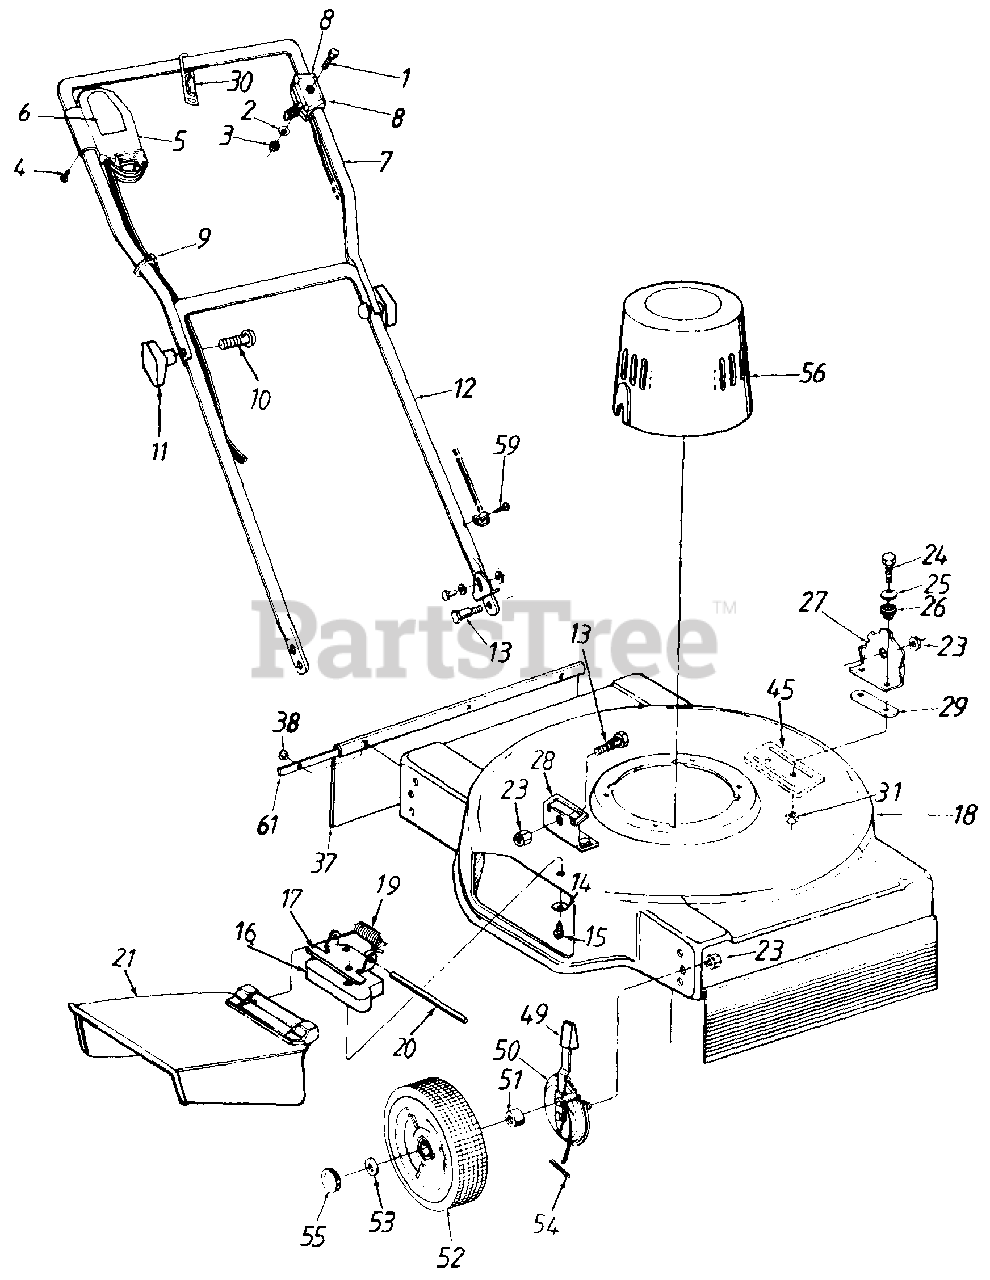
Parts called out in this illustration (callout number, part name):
1	Hex Bolt 1/4-20 x 1.5" Lg.
2	Fl-Wash. .281" I.0. x .5" O.D.
3	Acorn Nut 1/4-20 Thd.
4	Self-Tap Scr. #7 x 1" Lg.
6	Label - Switch Box
7	Upper Handle
8	Control Flip Knob
9	Cable Tie
10	Curved Carr. Bolt 5/16-18 x 2" Lg.
11	Hand Knob
12	Lower Handle
13	Shld. Bolt 3/8-16 Thd.
14	Bell-Wash. 1/4" I.D.
15	Self-Tap Scr. 1/4-20 x 1.12" Lg.
16	Spacer
17	Adapter Plate
20	Hinge Pin
21	Chute Deflector Ass'y.
23	Hex Sems Nut 3/8-16 Thd.
24	Hex Bolt 1/4-20 x 1" Lg.
25	Fl-Wash. .26" I.D. x .72" O.D.
26	Insulator Shield
27	Handle Brkt.- L.H.
28	Handle Brkt.- R.H.
29	Insulator Strap
30	Cord Restraint
31	Hex Nylon Lock Nut 1/4-20 Thd.
37	Flap - Rear & Front
38	Pop Rivet .188" Dia.
45	Deck Reinforcement Plate
50	Height Adj. Ass'y. (RF/LR)
51	Plastic Wheel Spacer
52	7" Wheel
53	Fl-Wash. .531" I.D. x.875" O.D.
54	Cotter Pin 3/32" Dia. x .75" Lg.
55	Hub Cap
56	Motor Cover
59	Self-Tap AB-Tap Scr. #10-16 x .5" Lg.
61	Latch
